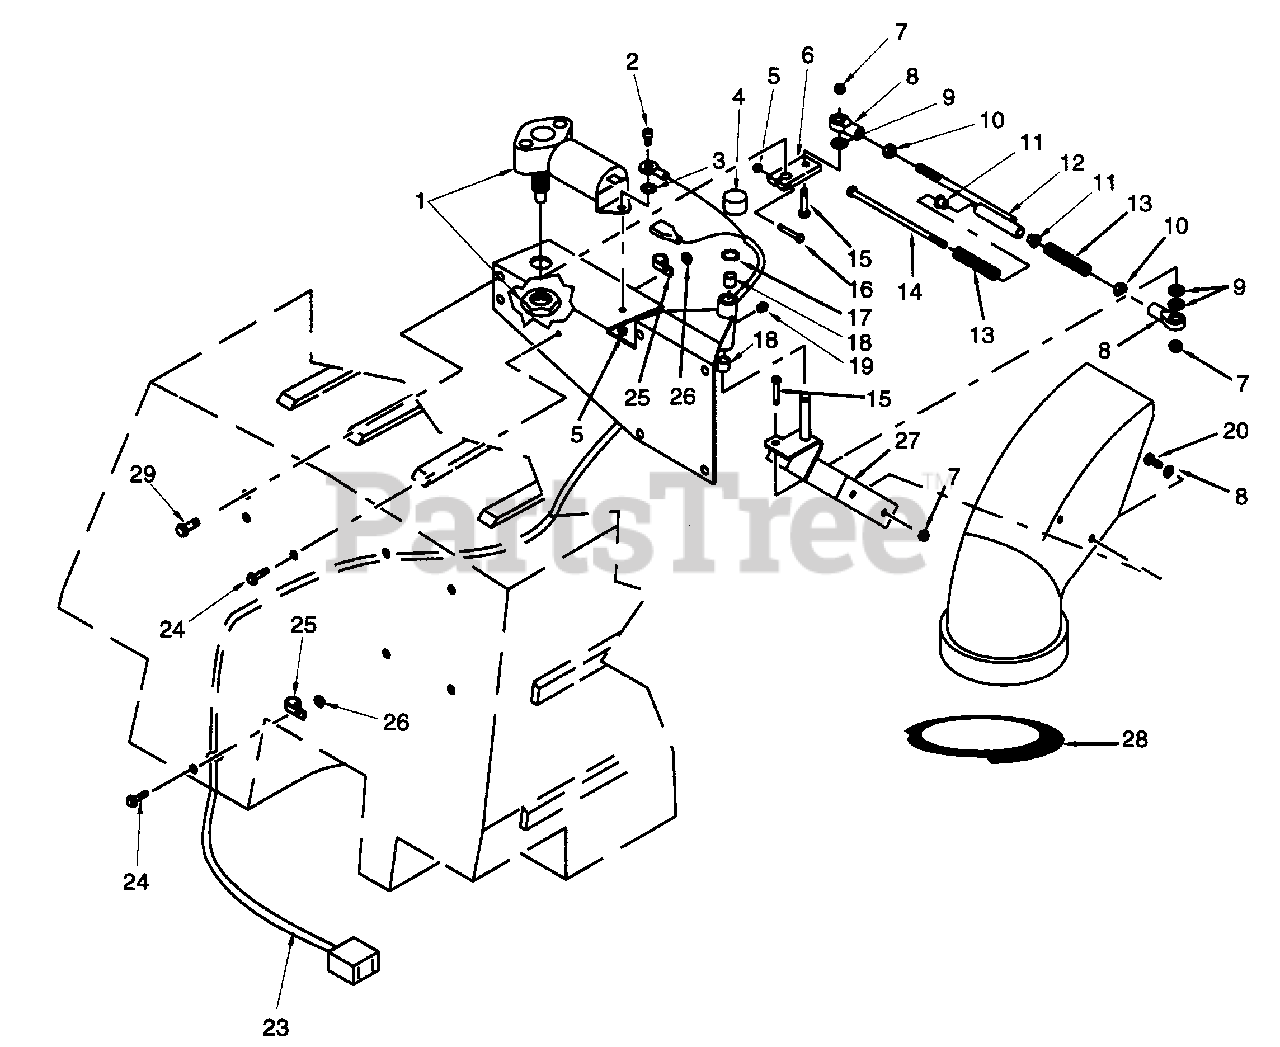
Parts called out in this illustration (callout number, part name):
1	MOTOR, ACTUATOR
2	CAPSCREW, SOCKET HEAD, #10-32 X 1/2
3	WASHER, EXTERNAL
4	CAP, PLASTIC
5	HEX LOCKNUT, ELASTIC STOP, #10-32
6	LEVER, ACTUATOR
7	HEX LOCKNUT, ELASTIC STOP, 5/16-18
8	ROD END, 5/16-18 R.H. THREAD
9	FLATWASHER, 5/16(.375 X .875 X .083)
10	HEX NUT, 5/16-18
11	BUSHING, NYLON
12	CONNECTING ROD
13	SPRING, CONNECTING ROD
14	BOLT, HEX HEAD, 5/16-18 X 7.00
15	BOLT, HEX HEAD, 5/16-18 X 1-1/4
16	CAPSCREW, SOCKET HEAD, #10-32 X 1-1/2
17	RETAINER RING
18	BUSHING, OILITE, .502ID
19	GREASE FITTING
20	BOLT, HEX HEAD, 5/16-18 X 3/4
23	WIRE HARNESS, HOPPER
24	SERR. FL. HEX HEAD CAPSCREW, 1/4-20 X 3/4
25	CLAMP, CABLE, 1/2
26	SERR. FL. HEX NUT, 1/4-20
27	PIVOT, ELBOW
28	SEAL, HOPPER ELBOW
29	BODY BOLT, 5/16-18 X .81
